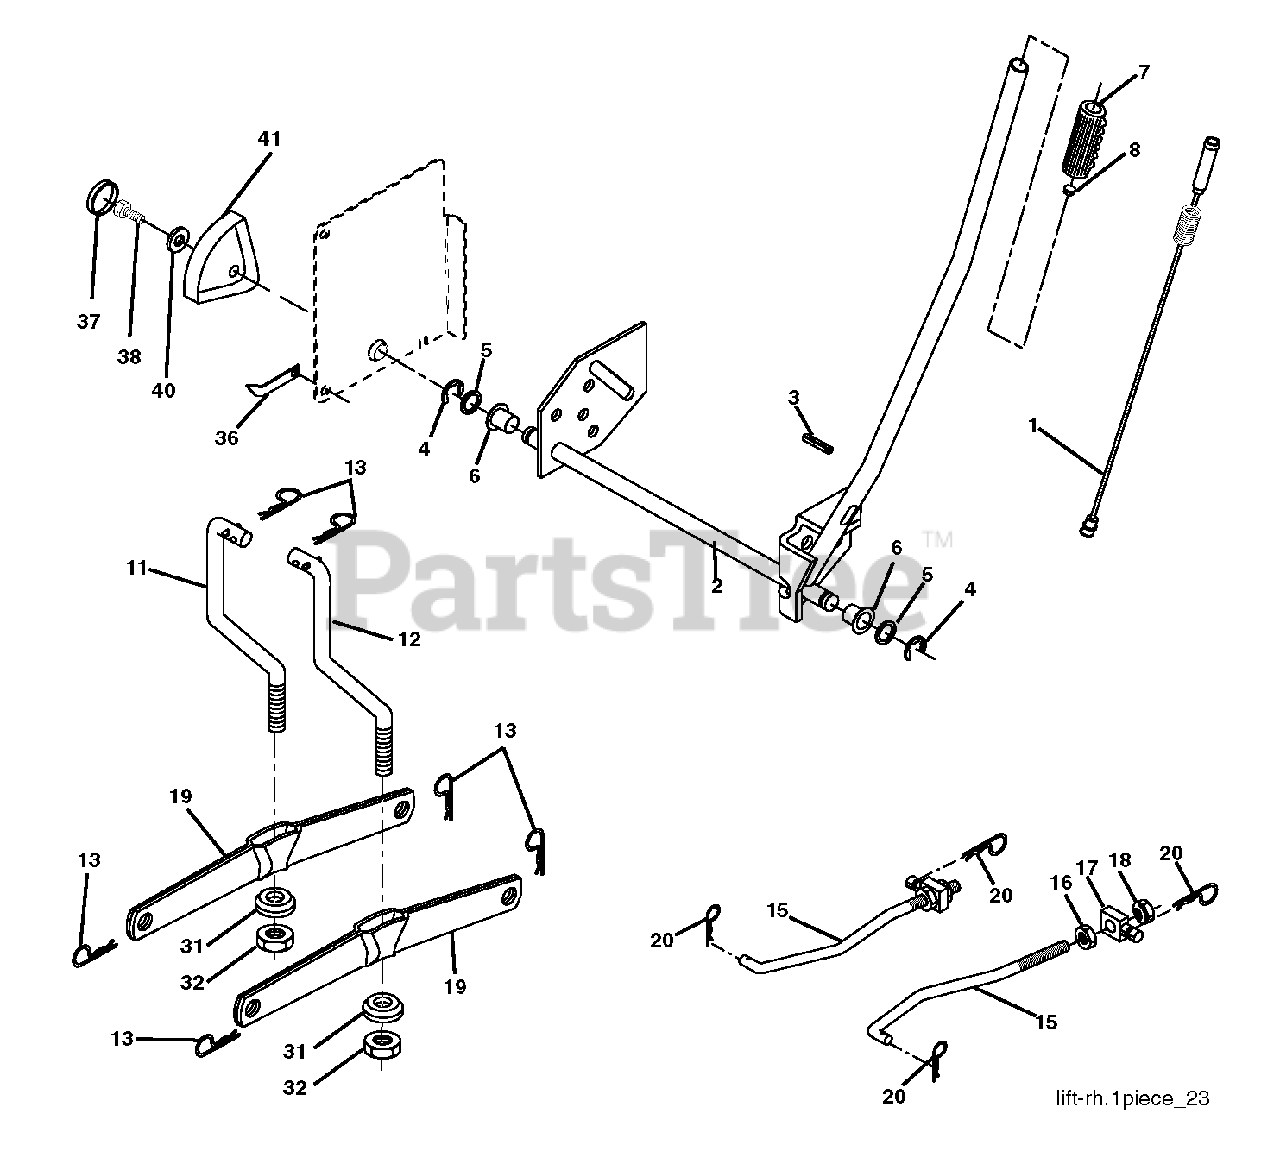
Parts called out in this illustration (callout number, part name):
1	PLUNGER.ASM.LIFT.LVR.BLK.17.32
2	SHAFT ASM R HANDLE
4	RETAINING RING LT
6	BEARING.NYLON
7	GRIP
8	PLUNGER BUT KIT
11	LINK
12	LINK
13	RETAINER-SPRNG RB
15	LINK.SUSPENSION.FRONT
16	NUT
18	NUT
19	ARM.REAR.SUSPENSION
20	PIN.COTTER.7/16.BOW TI
31	BEARING.PIVOT.LIFT
32	NUT CROWNLOCK 3/8-24
36	POINTER, HEIGHT INDICATOR
38	SCREW 5/16-18X1
41	HEIGHT INDICATOR
